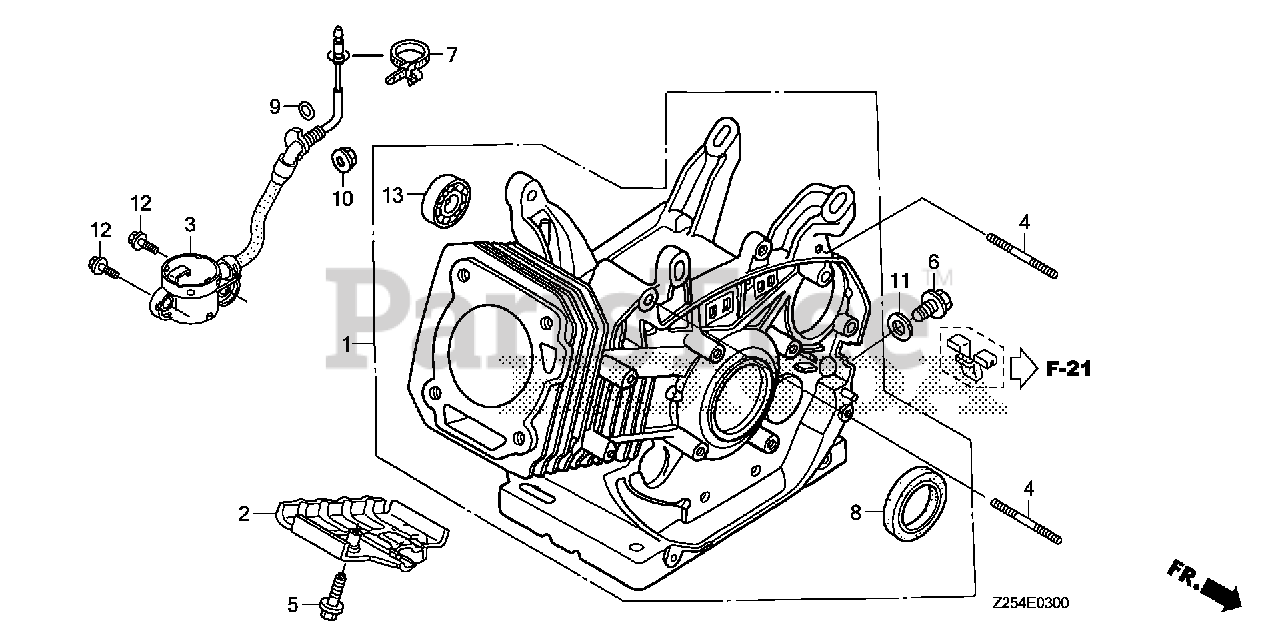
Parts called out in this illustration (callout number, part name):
1	CYLINDER ASSY.
2	SHROUD, ENGINE
3	SWITCH ASSY., OIL LEVEL
4	BOLT, STUD (6X30)
5	BOLT, FLANGE (6X25) (CT200)
6	BOLT, DRAIN PLUG (12X15)
7	BAND, INSERT WIRE
8	OIL SEAL (35X52X8) (NOK)
9	O-RING (13.5X1.5) (ARAI)
9	O-RING (14MM) (NOK)
10	NUT, FLANGE (10MM)
11	WASHER, DRAIN PLUG (12MM)
12	BOLT, FLANGE (6X12)
13	BEARING, RADIAL BALL (6202)
